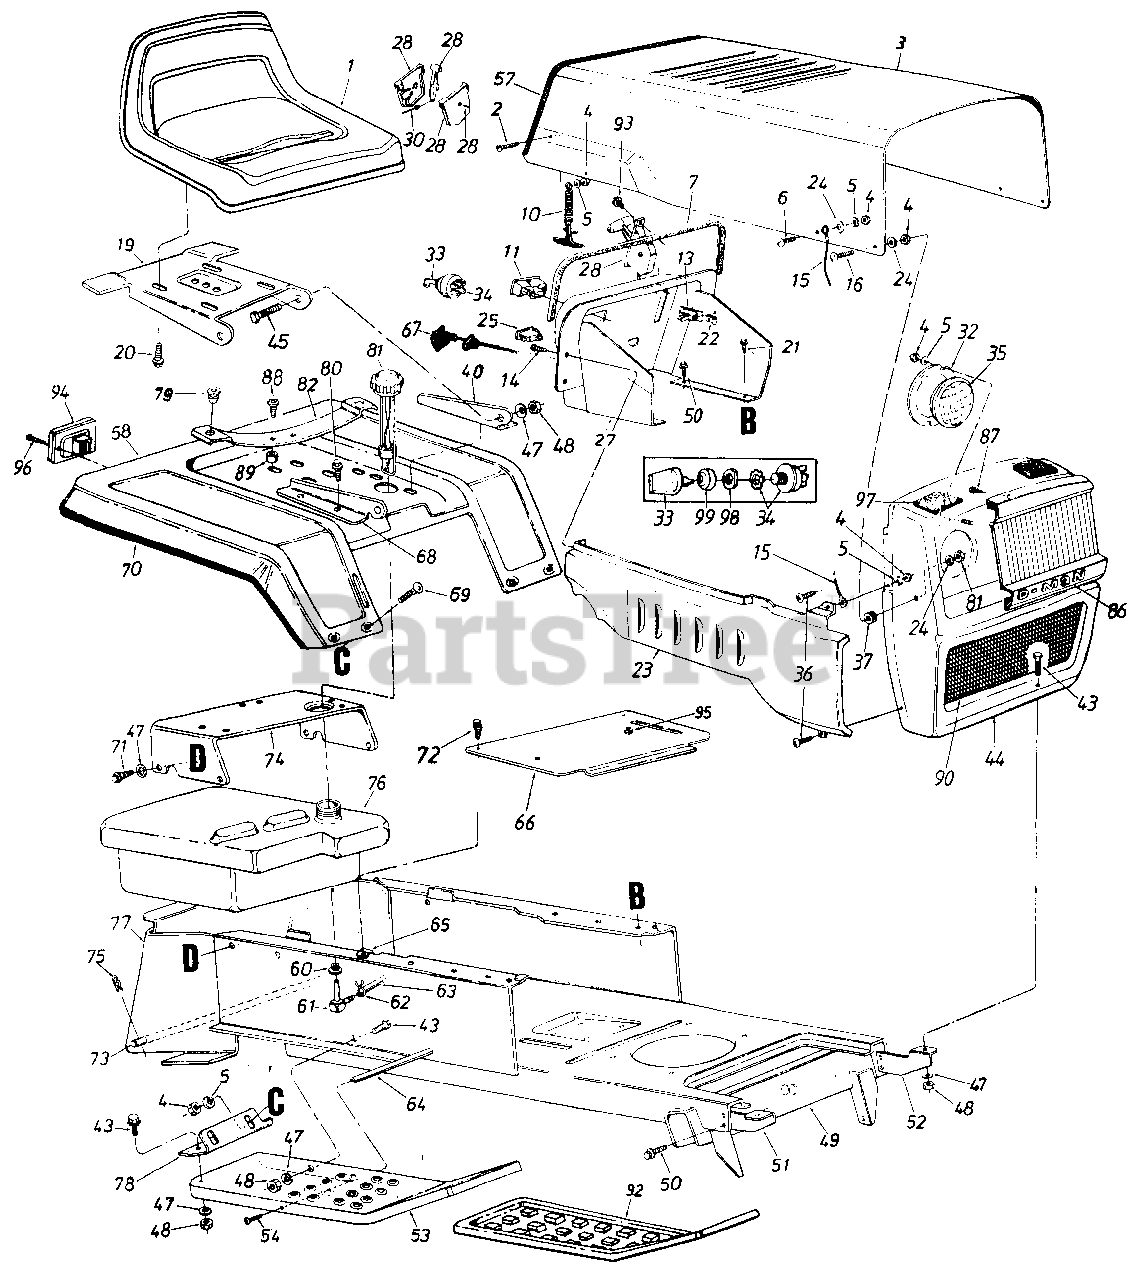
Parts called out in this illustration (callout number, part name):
1	Seat Assembly
2	Truss Mach. Scr. 1/4-20 x .50" Lg.
5	L-Wash. 1/4" Scr.
6	Truss Mach. Scr. 1/4-20 x .50" Lg.
7	Vinyl Molding Strip 29"
10	Hood Latch Ass'y.
11	Ammeter
13	Circuit Breaker
14	Hex Tap Scr. #10 x .50" Lg.
15	Hood Stop
16	Truss Mach. Scr. 1/4-20 x .75" Lg.
19	Seat Pivot Brkt.
20	Hex Wash. Hd. AB-Tap Scr. 318 x .75" Lg.
21	Hex Thd. Rolling Scr. 1/4" x .50" Lg.
22	Speed Nut #10Z
23	Grille Side Panel R.H.
24	Fl-Wash. 1/4" I.D.
25	Light Switch
27	Dash Panel Ass'y.
28	Throttle Control Box Comp.
30	Throttle Control Cable 35" Lg.
32	Head Lamp Retainer
33	Ignition Key
34	Ignition Switch
35	Head Lamp
36	Truss Machine Scr. 1/4-20 x .75" Lg.
37	Rubber Wash. .50" I.D. x 1.00 O.D. x .25 Thk.
40	Seat Bracket L.H.
43	Hex Scr. 5/16-18 x .75" Lg.
44	Grille Ass'y.
45	Shld. Bolt .437" Dia. x .162" Lg.
47	L-Wash. 5/16" I.D.
48	Hex Nut 5/16-18 Thd.
49	Lower Frame Ass'y.
50	Hex Thd. Rolling Scr. 5/16" x.75" Lg.
51	Grille Mount Brkt. R.H.
52	Grille Mount Brkt. L.H.
54	Truss Mach. Scr. 5/16-18 x .75" Lg.
57	Vinyl Moulding Strip 30"
58	Rear Fender
60	Bushing
61	90ø Nipple
62	Hose Clamp
63	Gas Line 46" Lg.
64	Running Board Rod
65	Speed Nut #10-24
66	Transmission Cover Ass'y.
67	Choke Control Comp.
68	Seat Bracket R.H.
69	Carr. Bolt 1/4-20 X .50" Lg.
70	Trim Strip 81" Lg.
71	Hex Thd. Rolling Scr. 5/16-24 x .75" Lg.
72	Truss Hd. Scr. #10 x .50" Lg.
73	Hitch Rod
74	Seat Mounting Channel
75	Internal Cotter Pin
76	Gas Tank
80	Hex Hd. Tap Screw
81	Gas Gauge
82	Seat Spring
86	Headlight Bezel
87	Self-Tap Scr. #8 x .5" Lg.
88	Hex Self-Tap Scr. 5/16-18 x 1.25" Lg.
89	Spacer
90	Grille Insert
92	Foot Pad
93	Truss Mach. AB-Tap Scr. #10 x .50" Lg.
94	Taillight
95	Snap Bushing
96	Truss AB-Tap Scr. #6 x .62" Lg.
97	Foam Strip
98	Ignition Switch Nut
99	Ignition Switch Cap
